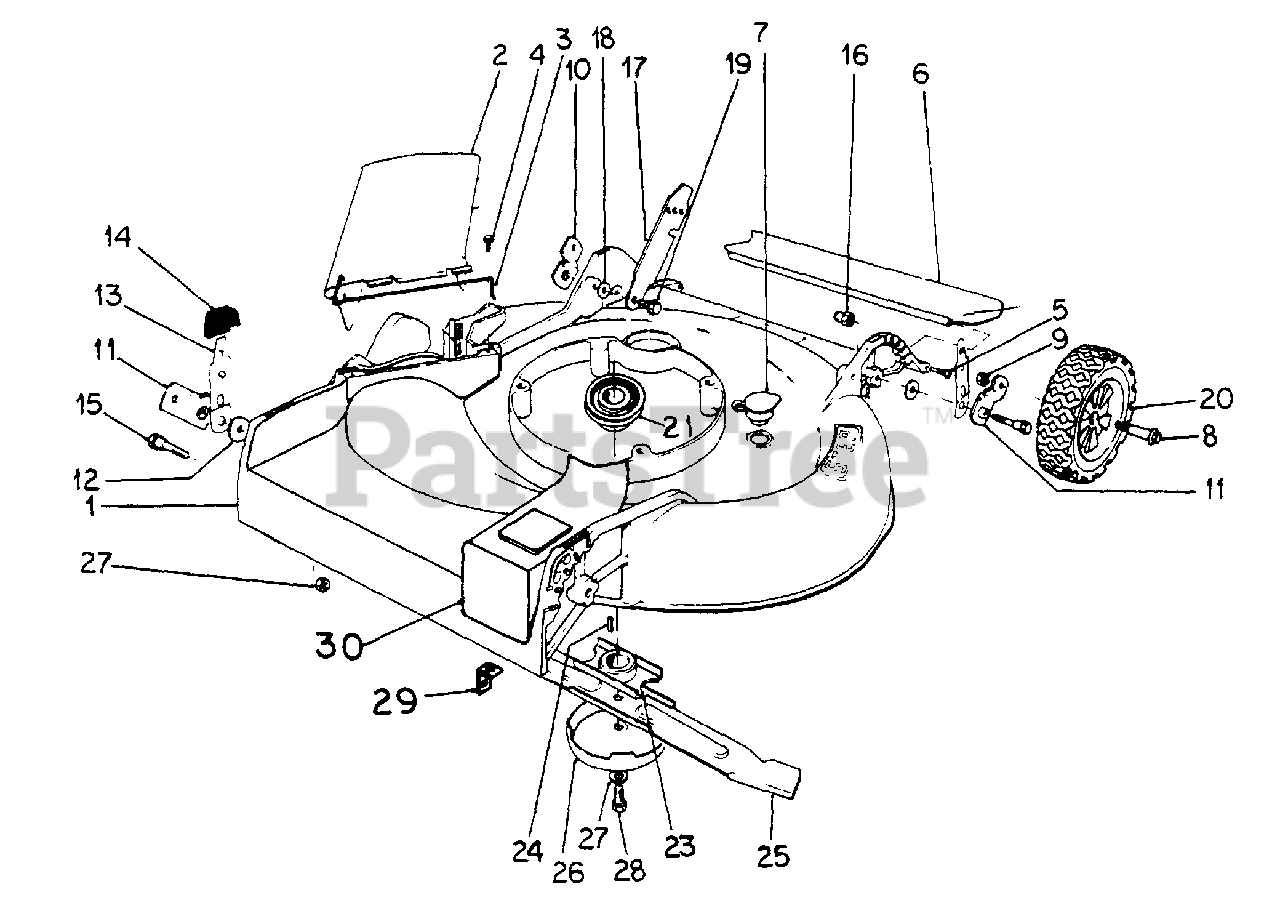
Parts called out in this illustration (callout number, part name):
1	HOUSING, MOWER
3	SPRING, HINGE
6	SHIELD, REAR
7	PLUG, WASH-OUT
8	BOLT, WHEEL
10	ARM, PIVOT -RIGHT REAR-
11	ARM, PIVOT -LEFT REAR-
13	ARM, SPRING
15	BOLT, PIVOT
16	NUT, 5/16-1B
17	LATCH, HANDLE
18	SPACER, HANDLE LATCH
19	BOLT, SHOULDER
19	SCREW, SHOULDER
20	WHEEL W/TIRE, REAR
21	PULLEY, DRIVE
23	RETAINER, BLADE
24	KEY, 3/16 X .50 SQ PARALLEL
25	BLADE, 21 IN. CUTTING
26	CLIP, ANTI-SCALP
27	WASHER, 7/16 PLN HV LOCK
28	BOLT, BLADE
29	BRACKET, ADJUSTING
30	COVER, DRIVE BELT
